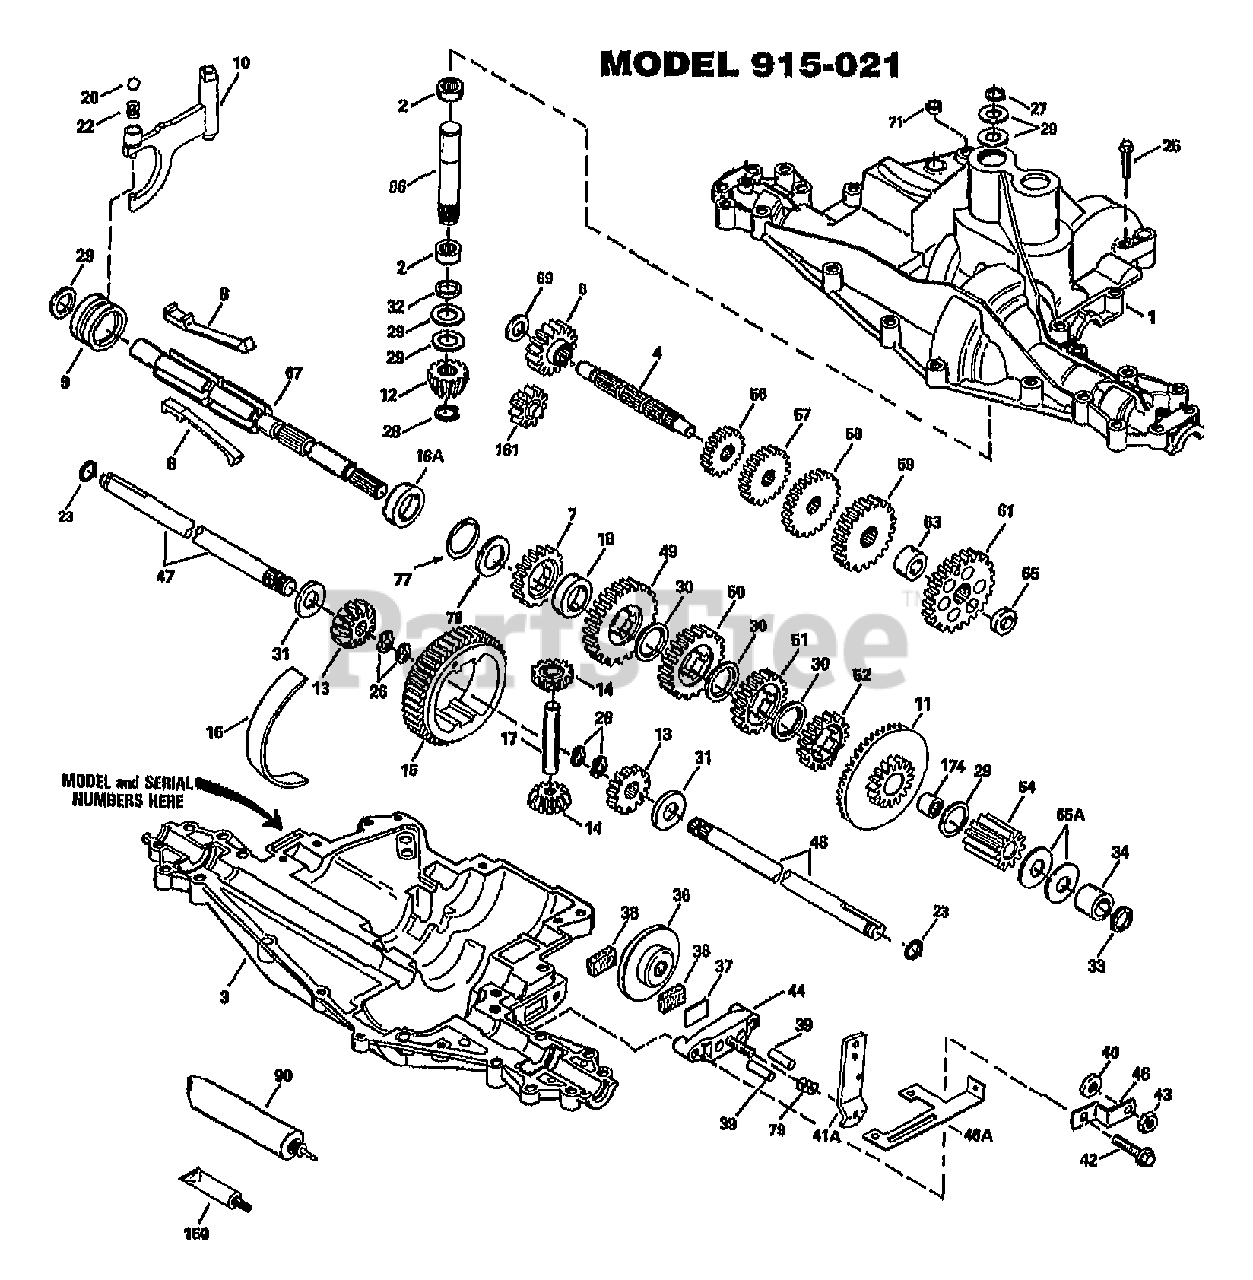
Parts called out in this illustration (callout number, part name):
1	TRANSAXLE COVER
2	NEEDLE BEARING
3	TRANSAXLE CASE
4	COUNTERSHAFT
6	SPUR GEAR(16 TEETH)
7	SPUR GEAR(22 TEETH)
8	SHIFT KEY
9	SHIFT COLLAR
10	SHIFT ROD & FORK
11	BEVEL GEAR & BEARING(INC. 174)
12	BEVEL PINION(14 TEETH)
13	BEVEL GEAR(16 TEETH)
14	DIFFERENTIAL PINION
15	RING GEAR
16	BEARING STRIP
17	DRIVE PIN
18	NEUTRAL SPACER
18A	NEUTRAL SPACER
20	STEEL BALL,5/16* DIA
22	SPRING
23	SEAL RING
25	SCREW, 1/4-20X1-1/4"
26	RETAINING RING
27	RETAINING RING
28	RETAINING RING
29	WASHER
30	WASHER
32	"O"RING
36	BRAKE DISK
37	BRAKE PAD PLATE
38	BRAKE PAD (PKG. OF 2)
39	DOWEL PIN
41A	BRAKE LEVER
42	SCREW, 1/4-20X1-1/4"
43	LOCKNUT, 5/16-24
44	BRAKE PAD HOLDER
46	BRAKE LEVER BRACKET
46A	BRAKE BRACKET
47	AXLE (16-1/4" LONG)
48	AXLE (11" LONG)
49	SPUR GEAR (32 TEETH)
50	SPUR GEAR (27 TEETH)
51	SPUR GEAR (25 TEETH)
52	SPUR GEAR (22 TEETH)
54	SPUR GEAR (11 TEETH)
56	SPUR GEAR (18 TEETH)
57	SPUR GEAR (23 TEETH)
58	SPUR GEAR (25 TEETH)
59	SPUR GEAR (28 TEETH)
61	SPUR GEAR (34 TEETH)
66	INPUT SHAFT
67	SHIFTER & BRAKE SHAFT
71	SQUARE CUT RING
77	INVERTED RETAINING RING (PKG. OF 2)
90	GREASE (32 OZ. BTL. BENTONITE GREASE)
150	GASKET ELIMINATOR (LOCTITE #515)
161	REVERSE IDLER
174	NEEDLE BEARING
